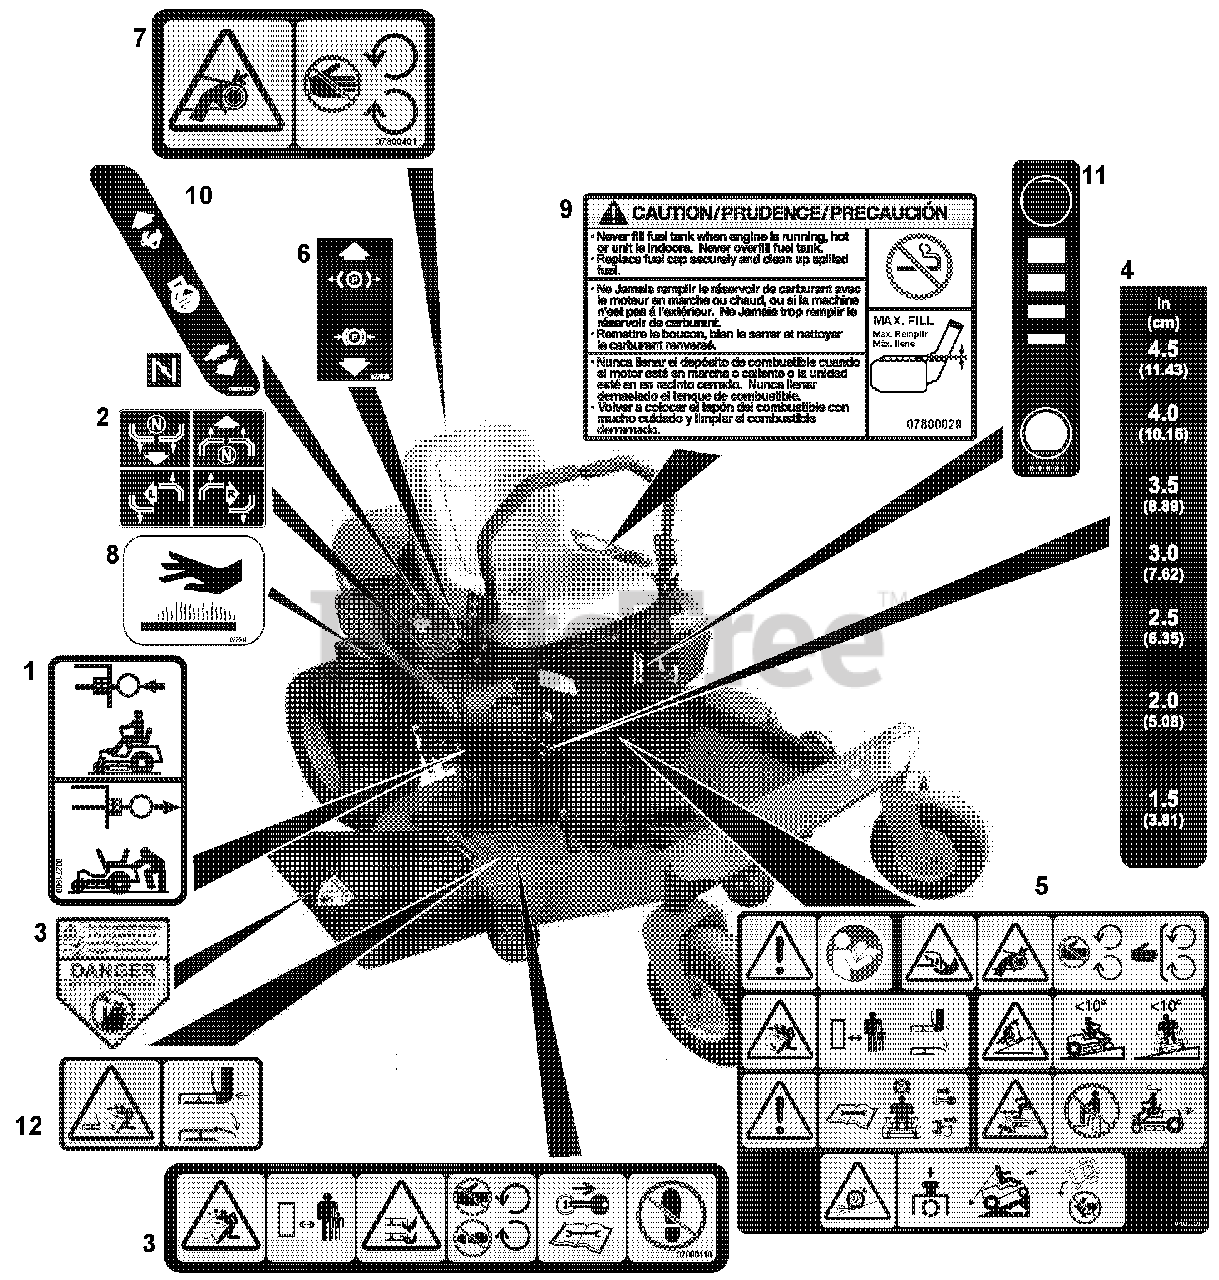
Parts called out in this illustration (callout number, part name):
1	DECAL, TRANSMISSION DISCONNECT
2	DECAL, INSTRUCTIONAL-STEERING
3	DECAL, DECK SAFETY
4	DECAL, HEIGHT OF CUT
5	DECAL, MAIN SAFETY
6	DECAL, PARKING BRAKE LEVER
7	DECAL, SAFETY - GUARDING
8	DECAL, HOT SURFACE
9	DECAL-FUEL, WARNING
10	DECAL, SPEED CONTROL
11	DECAL, FUEL LEVEL
12	DECAL, TRAILER HITCH
13	DECAL, SAFETY - DECK GUARDING
